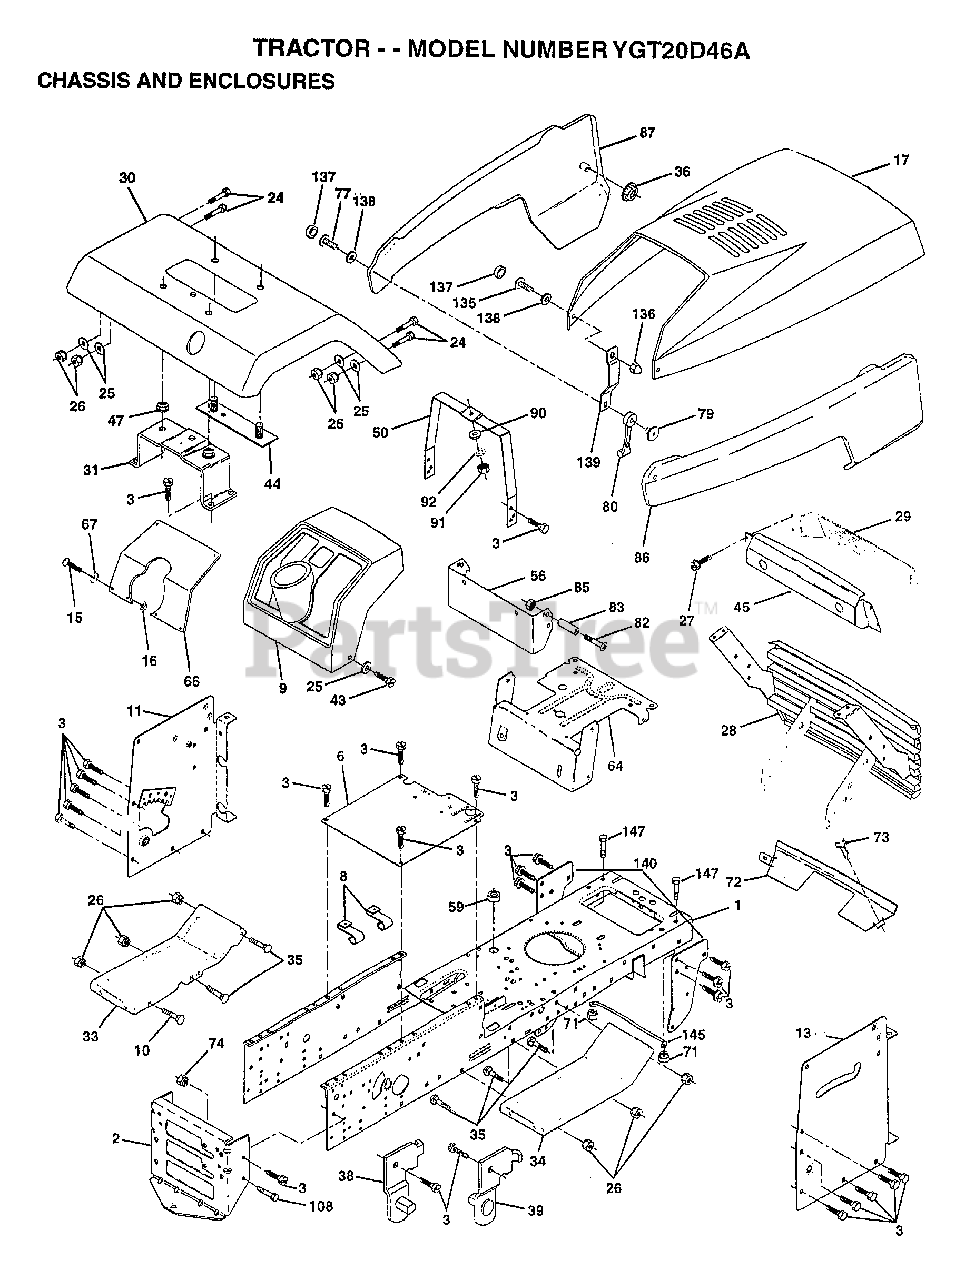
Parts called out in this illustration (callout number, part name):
1	CHASSIS ASM
3	SCREW
6	SADDLE
8	"CLIP,INSULATOR"
9	DASHBOARD BLACK
11	PANEL.DASH.LH.PNT
13	PANEL.DASH.RH.PNT
15	SCREW
17	"HOOD, YARD PRO"
24	BOLT
25	WASHER
26	NUT
28	GRILLE ASM PNT
29	LENS.BAR.CLEAR
30	"FENDER WS,FTK"
31	BRKT.ASM.FENDER
33	FOOTREST PNT LH
34	FOOTREST.RH.LT/GT
35	BOLT
36	PAL NUT LT
38	BRACKET ASM LH
39	BRACKET ASM RH
43	SCREW
44	STRAP ASM FENDER
45	BEZEL.ASM.
47	NUT-PUSH YT
50	DASH.SUPT.YP/HUSQ
56	EXT DASH LTYT
64	DASH.LOWER.LT
66	"PLATE DASH,SLKSCR"
67	WASHER
73	SCREW CRT
77	SCREW
79	WELDNUT
80	HOOD LATCH T
82	SCREW
83	SPACER LT
86	"PANEL ASM SIDE,RH"
87	"PANEL ASM-SIDE,LH"
90	WASHER PM
92	LOCKWASHER
135	SCREW.10-24X3/8.
136	ACORN NUT RB
137	SNAP CAP LT
138	WASHER LT
139	BKT.SPT.HOOD/PANL
140	BRKT SUSPENSION
145	"ROD POVOT,CHASSIS"
147	BOLT LT
